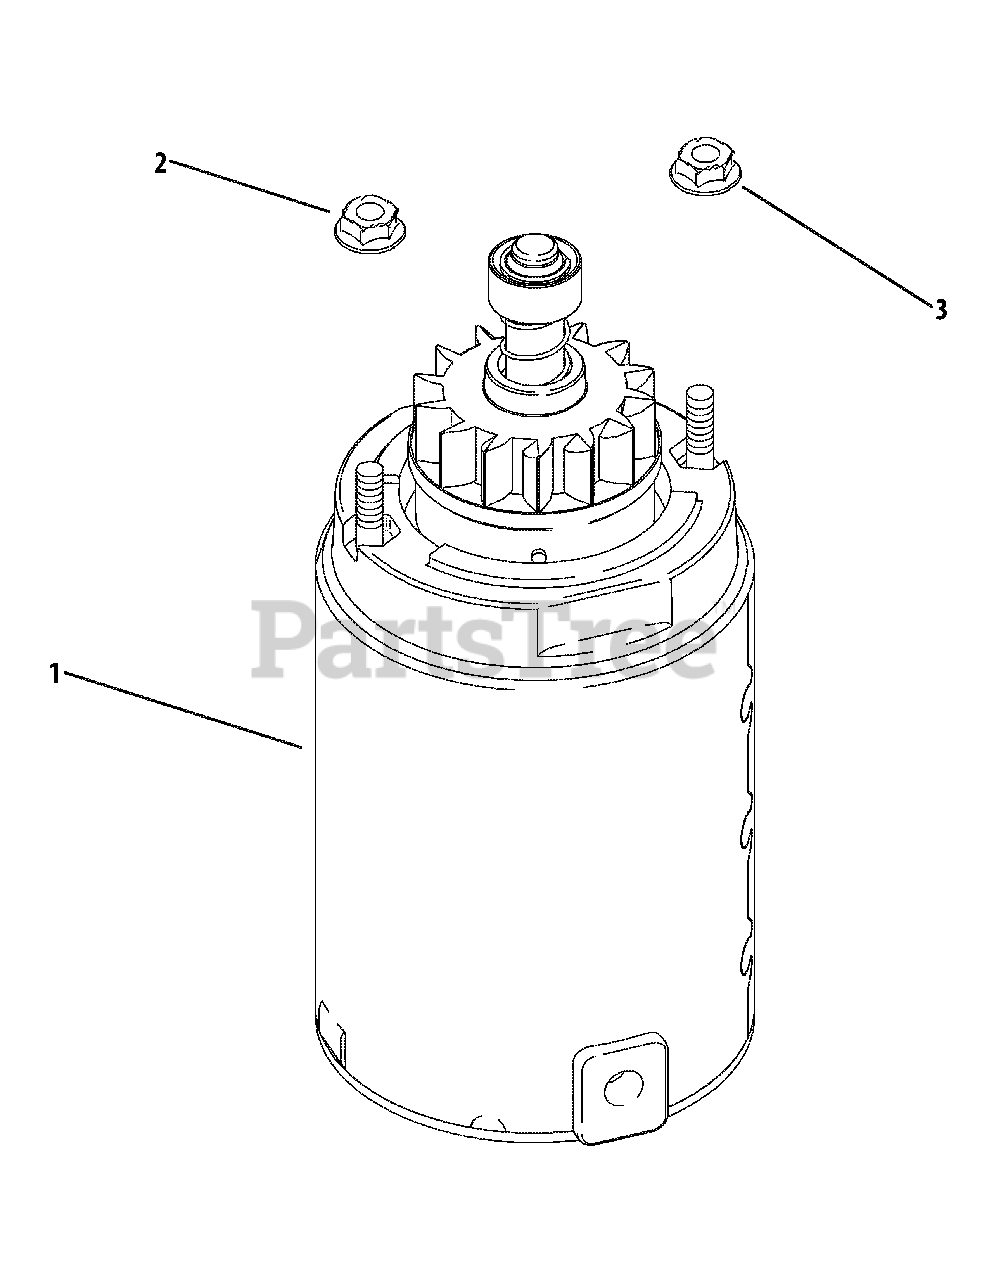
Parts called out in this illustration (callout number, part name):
1	Starter Assembly
2	Free Spinning Flg Nut, #10-24
3	Hex Flg Nut, 1/4-20"
